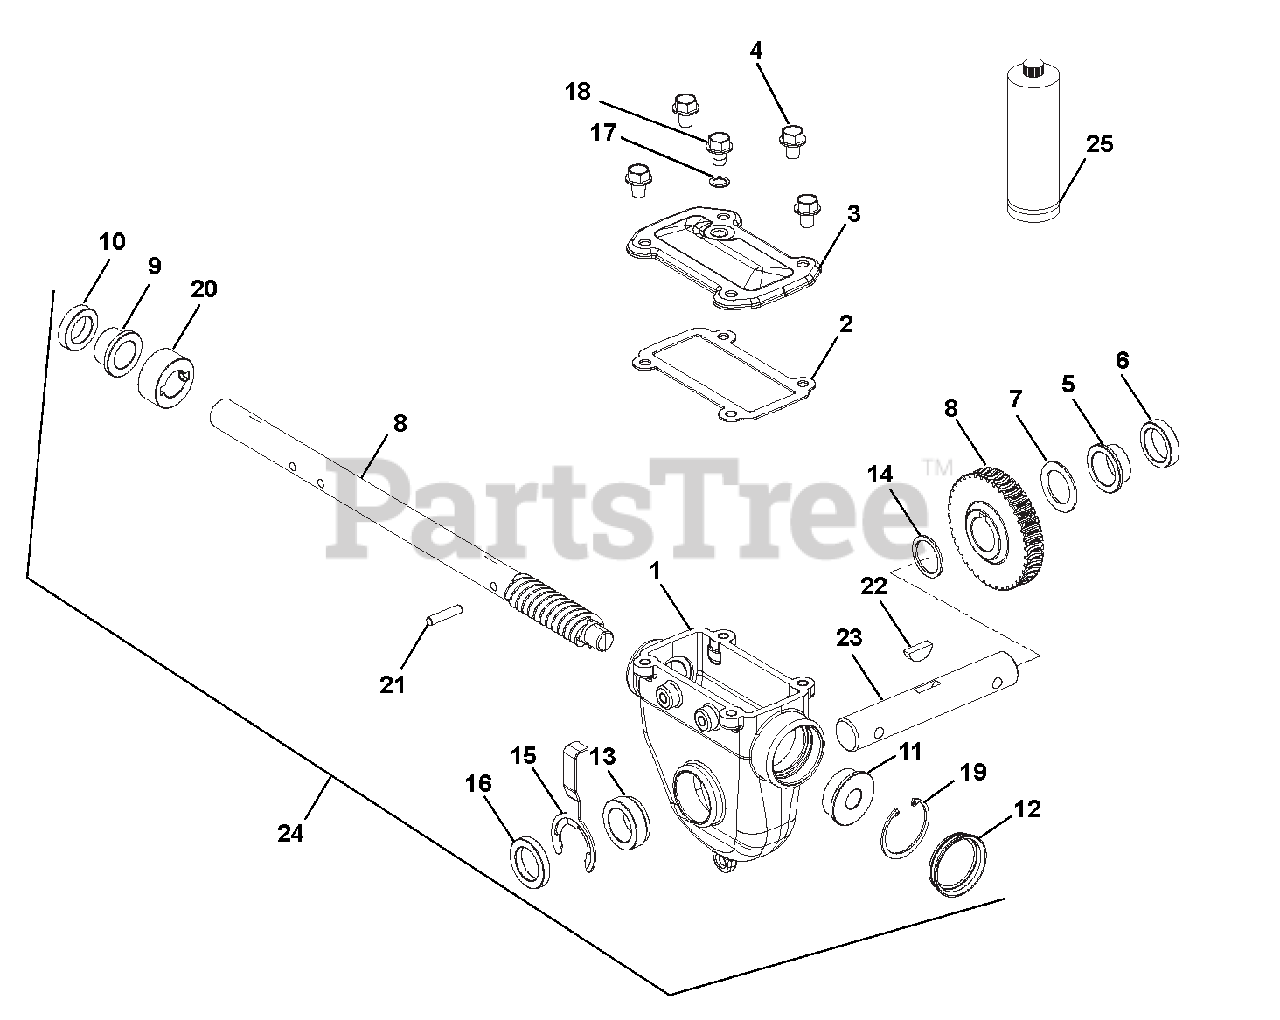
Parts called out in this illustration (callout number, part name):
1	GEARCASE, LARGE MACHINED
2	GASKET, TOP - LARGE GEARCASE
3	COVER, TOP - LARGE IRON
4	BOLT, SEMS .31-18X.50 GR5 YWZC
5	BSHG-FLG 1.006X1.128X.555X1.45
6	SEAL-OIL .999X1.375X.312 TBC29
7	WSHR-FL-STL 1.010X1.505X.062YZ
8	WORM SHAFT & GEAR
9	BSHG-FLG .879X1.128X.75X1.45
10	SEAL-OIL .873X1.375X.312 TBC29
11	BSHG-FLG .628X1.503X.58X1.725
12	COVER, GEAR CASE 1.75"
13	BSHG-FLG LARGE, RIGHT
14	WSHR-FL-STL 1.010X1.250X.068YZ
15	BUSHING RETAINER, LARGE
16	SEAL-OIL .999X1.500X.250 TBC29
17	WSHR-BND-SEAL .38X.75X.11 GALV
18	@SCR-ROLOK .38-16X.50 HWH YWZC
19	RG-RTNG-INT 1.750X.062
20	THRUST COLLAR, .875"ID SLIPFIT
21	PIN-STR .250X1.12 6150
22	KEY-WDRF .25X.875 HRD #A
23	RAKE SHAFT, SHORT-COMMON
24	GEAR CASE ASSY - DLX IRON
25	ARIENS L3 LUBE, 8 OZ BOTTLE
